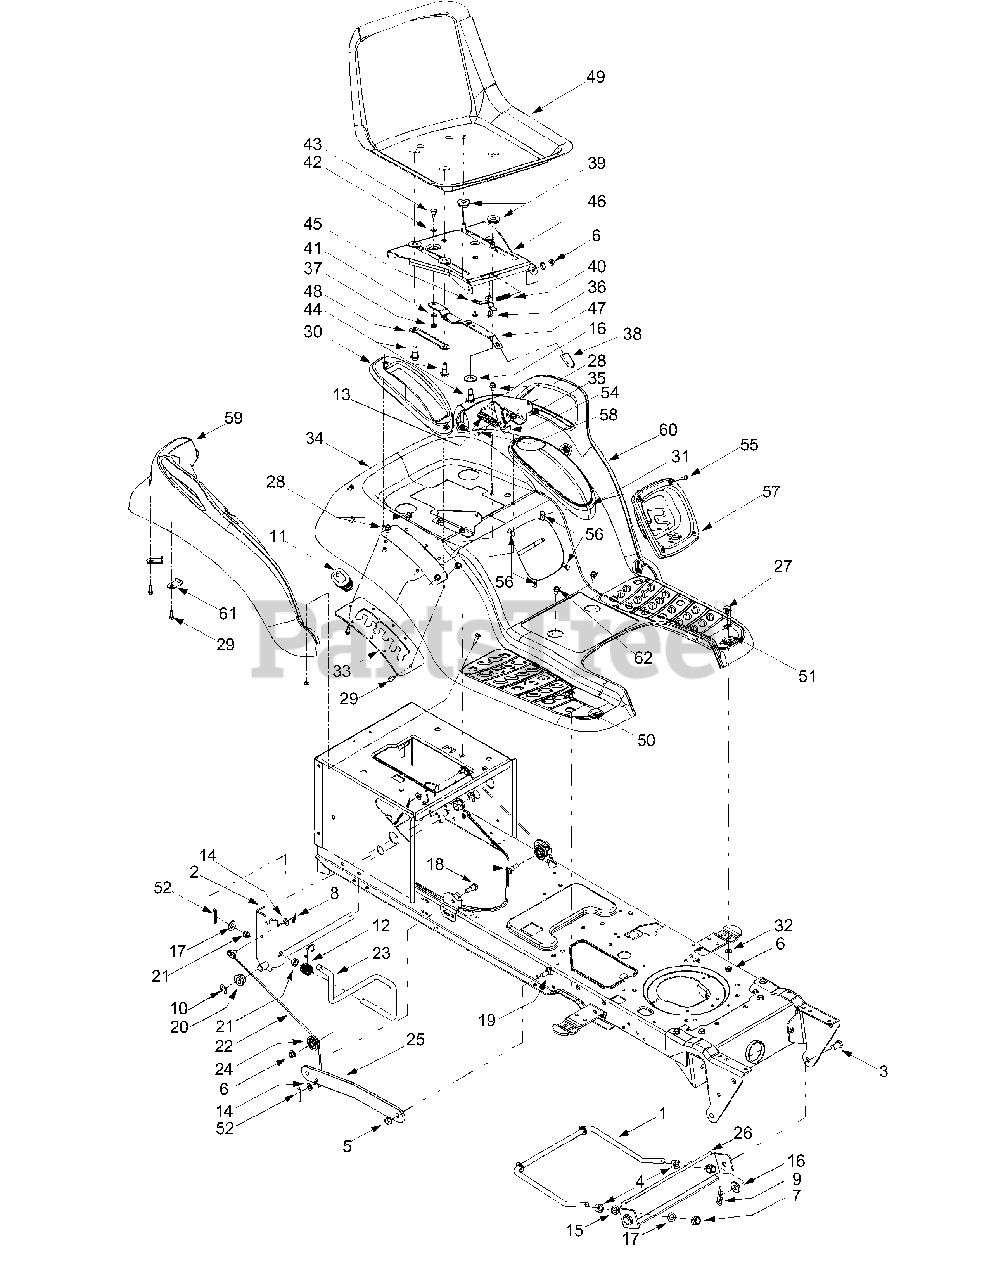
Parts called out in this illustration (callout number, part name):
1	Deck Stabilizer Rod (Model 808H)
2	Lift Shaft Assembly (Model 808H)
3	Clevis Pin, .5 x .78
4	Hex Nut, 1/2-13
5	Flange Lock Nut, 3/8-16
6	Lock Nut, 5/16-18
7	Hex Nut, 1/2-13
8	Internal Cotter Pin
9	Internal Cotter Pin
10	E-Ring
11	Handle Grip
12	Torsion Spring
13	Extension Spring, .84 x 4.6
14	Flat Washer, 5/16
15	Lock Washer, 1/2
16	Flat Washer, .31 x 1.062 x .134
17	Flat Washer, .51 x 1.12 x .06
18	Hex Cap Screw, 5/16-18 x .62
19	Shoulder Screw, 3/8-16
20	Hex Flange Bearing
21	Snap Flange Bearing
22	Lift Cable, 16.16
23	Lift Handle
24	Roller Pulley
27	Carriage Bolt, 5/16 x .62
28	AB Screw, 5/16-12 x .75
29	Self-tapping Screw, 1/4-15 x .75
30	Lift Lever Cover
31	Cover w/ Cup Holder
32	Flat Washer, .349 x 1.0 x .063
33	Lift Adjustment Bracket
36	Screw, #10-16 x .375
37	Hex Flange Lock Nut, 1/4-20
38	Seat Adjuster Grip
39	Spacer
40	Compression Spring, .41 x 1.5
41	Spring Washer, .265 x .562 x .025
42	Flat Washer, .344 x .62 x .03
43	Shoulder Screw, .340 x .285,1/4-20
44	Shoulder Screw, .50 x .50, 3/8-16
45	Seat Stop
48	Seat Adjustment Selector
49	High Back Seat, Black
50	RH Foot Pad
51	LH Foot Pad
51	Foot Pad Clips
52	Cotter Pin
54	Seat Lift Bracket
55	Phillips Pan Screw, 1/4-20 x .75
56	U-type Speed Nut, 1/4-20
57	Shift Lever Cover
58	Shoulder Screw, .437 x .286
59	RH Fender Flare
60	LH Fender Flare
61	Fender Clips
62	TT Screw 1/4-20 x 0.5
